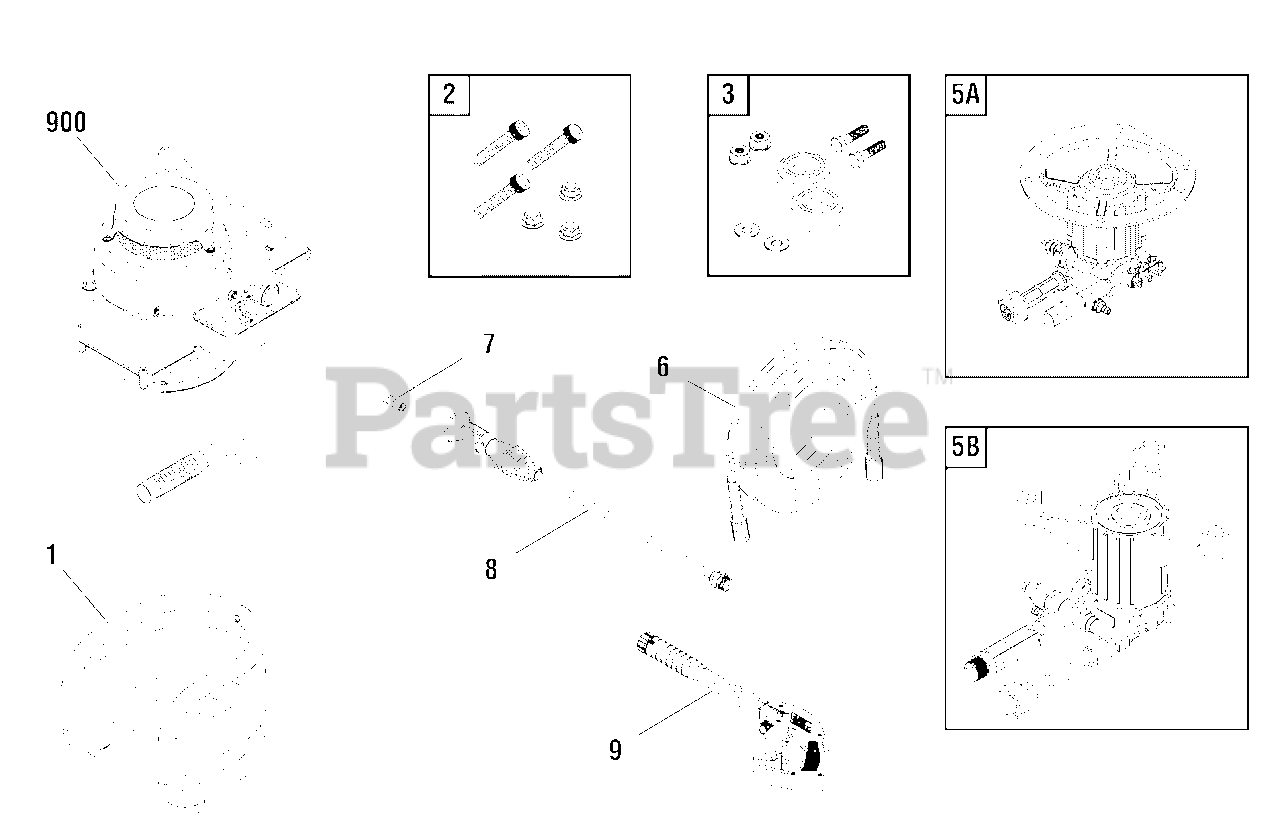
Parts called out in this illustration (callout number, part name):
1	Assy, Base w/Mounts
2	Kit, Pump/Engine Mounting Hardware
3	Kit, Vibration Mount
5A	Pump
6	Hose
8	Assy, Wand Adjustable
9	Gun
900	* Engine
